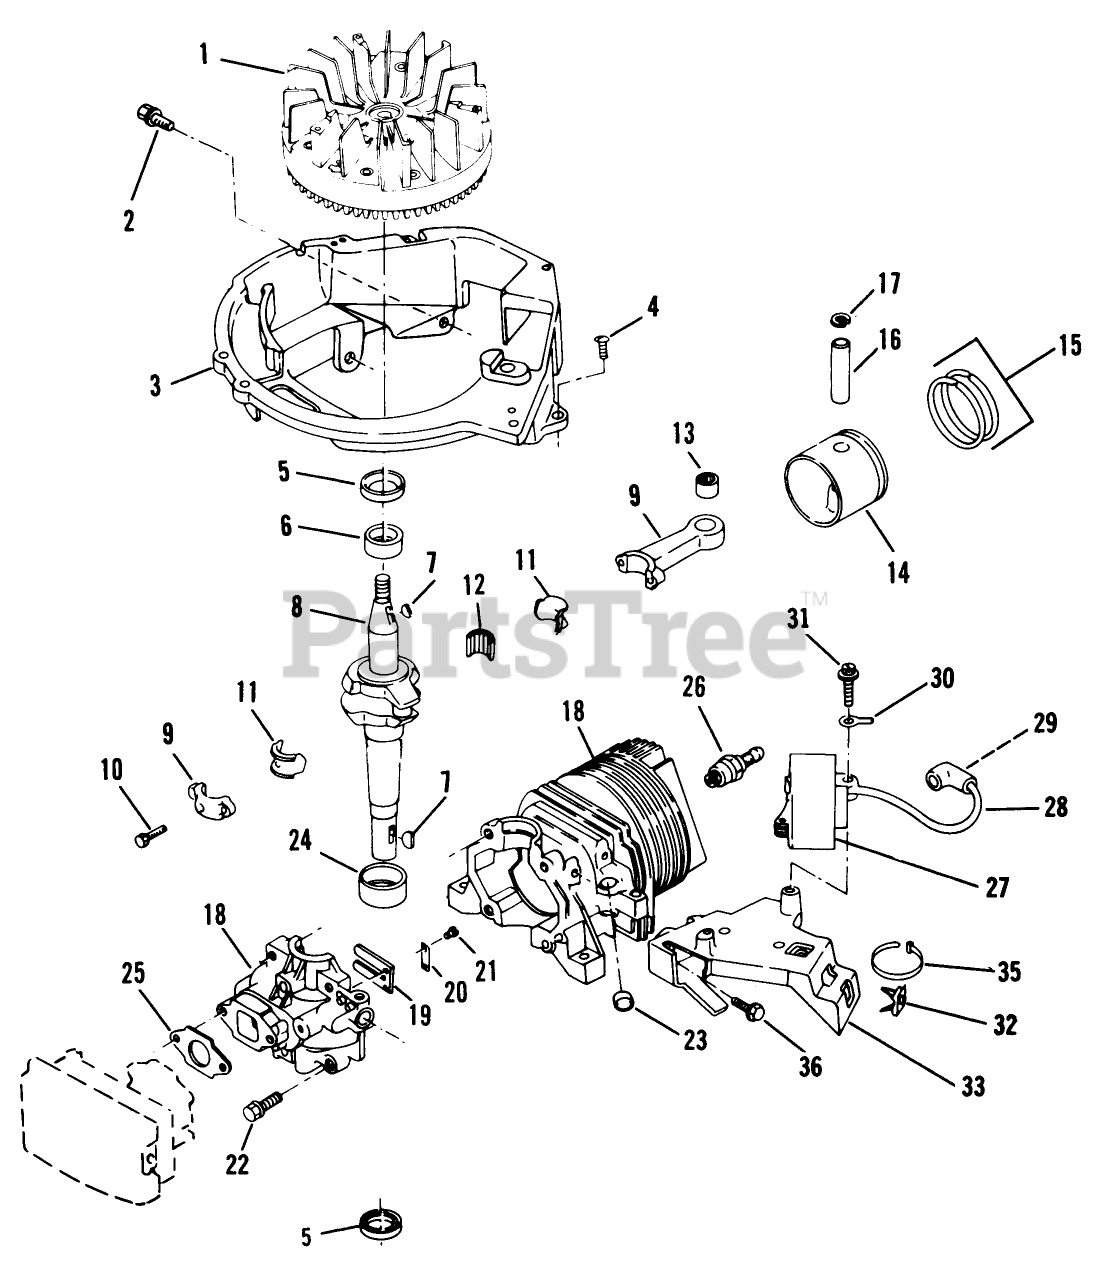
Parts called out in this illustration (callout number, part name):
2	SCREW-SEMS
4	SCREW F
5	SEAL-OIL
6	BEARING V
7	KEY
10	SCREW-HSH
11	LINER ASM
12	BEARING-NEEDLE
13	BEARING AY F
17	RING-RETAINING
20	PLATE-BACKUP, REED
21	SCREW-HH
22	SCREW S
23	PLUG-CORE VF
24	BEARING V
25	GASKET CARB S
28	HT LEAD&COVER XEV
30	TERMINAL S
32	NUT-CLIP
33	BRACKET S
